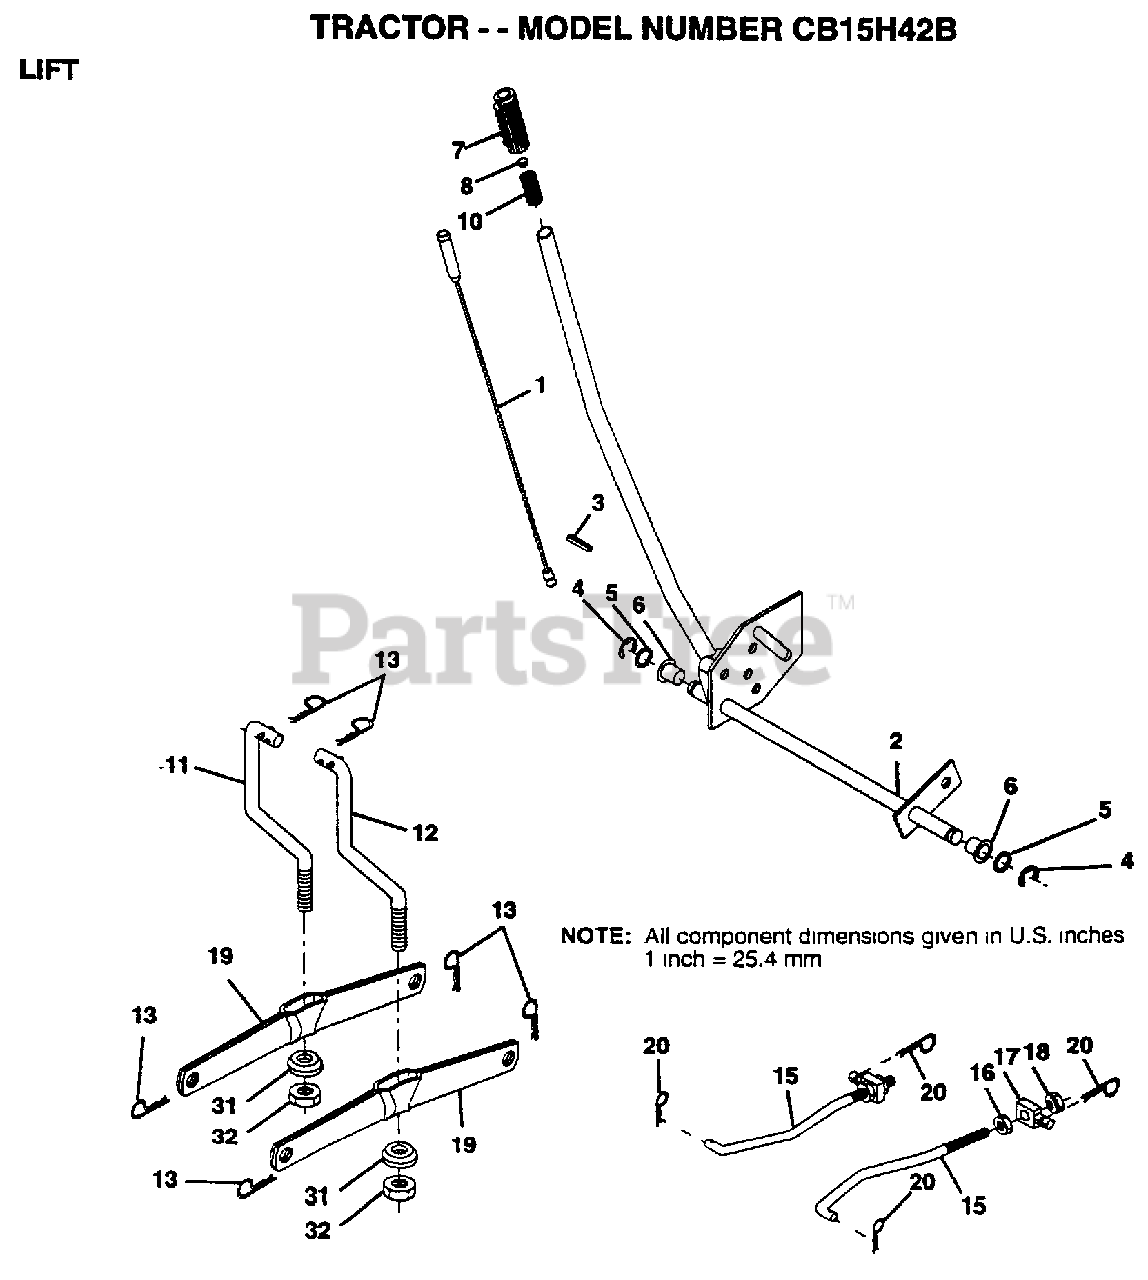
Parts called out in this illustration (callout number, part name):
1	WIRE ASM
2	HANDLE.LIFT.LH.
3	PIN GROOVE
5	WASHER
6	NYLON BEARING
7	GRIP
15	LINK.FRONT
16	NUT
17	TRUNION
18	NUT.LK.W/WSH.1/2.
19	ARM SUSP REAR
20	RETAINER.SPRING
31	BEARING PVT LH
32	NUT.CROWNLOCK.3/8
